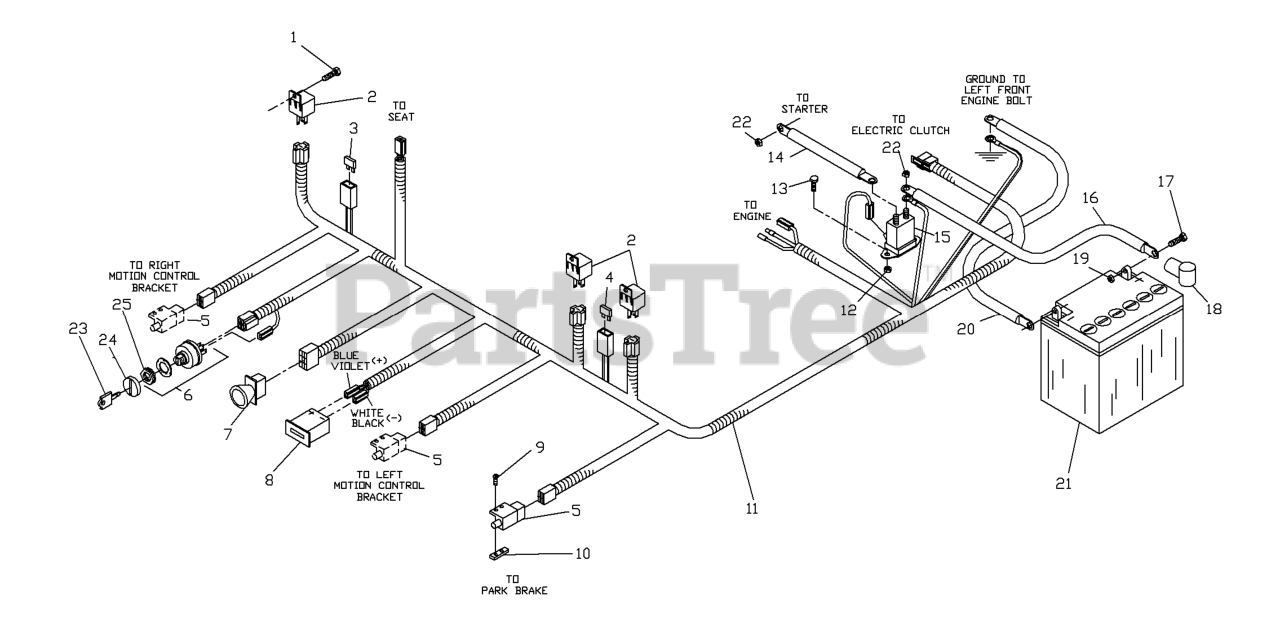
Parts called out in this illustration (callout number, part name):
1	SCREW #10 X 1/2 SELF TAPPING
3	FUSE, 7.5 AMP 32 VOLT ATO
4	FUSE, 20 AMP 32 VOLT ATO
5	SWITCH, INTERLOCK
6	IGNITION SWITCH KIT
7	RP.SWITCH, BLADE
8	HOUR METER
9	SCREW #10-24 X 5/8
10	TAPPED PLATE
11	WIRING HARNESS-KAW MINI
12	NUT 1/4C CENTERLOCK
13	HCS 1/4C X 5/8
14	CABLE POSITIVE
16	CABLE POSITIVE, LONG
17	HCS 5/16C X 3/4
19	NUT 5/16C CENTERLOCK
20	CABLE-NEGATIVE
21	BATTERY WET NOT SELLABLE
22	NUT.1/4-20.HEX.NYLOC.ZD
23	KEY-PADDED
24	CAP IGNITION NUT
25	DNO IGNITION NUT
